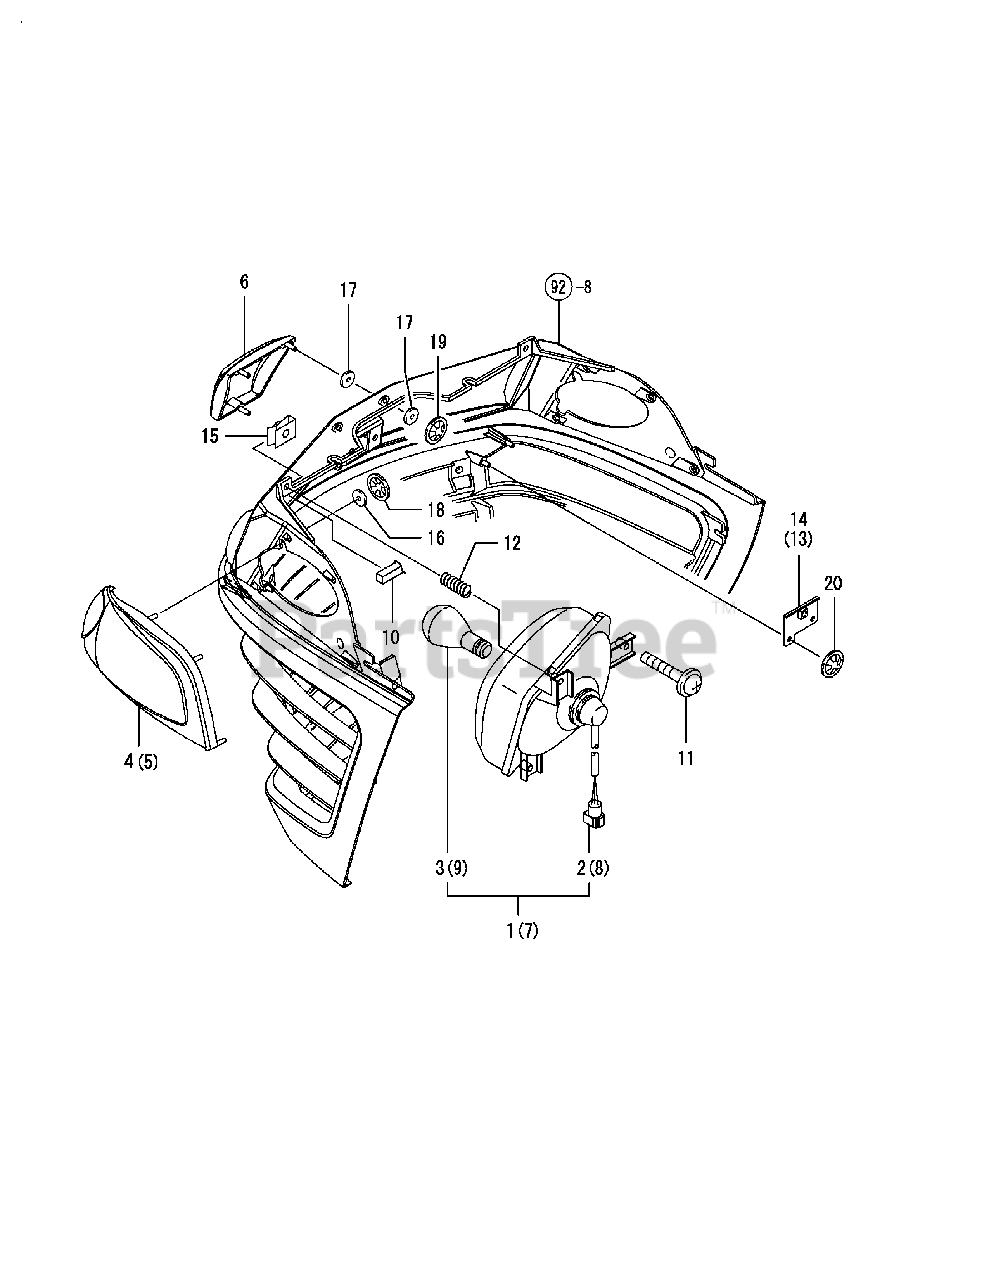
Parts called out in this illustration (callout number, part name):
1	HEADLIGHT ASSY, L.H.
2	WIRE ASSY, LEAD
3	BULB 12V45/45W
4	LENS, SIDE L.H
5	LENS, SIDE R.H
6	LABEL, CENTER LOGO
7	HEADLIGHT ASSY, R.H.
8	WIRE ASSY, LEAD
9	BULB 12V45/45W
10	SEAL, HEADLIGHT
12	SPRING, ADJUST
13	BRACKET ASSY, L
14	BRACKET ASSY, R
18	NUT M5,SPEED
19	NUT M5,SPEED
20	NUT M5,SPEED
